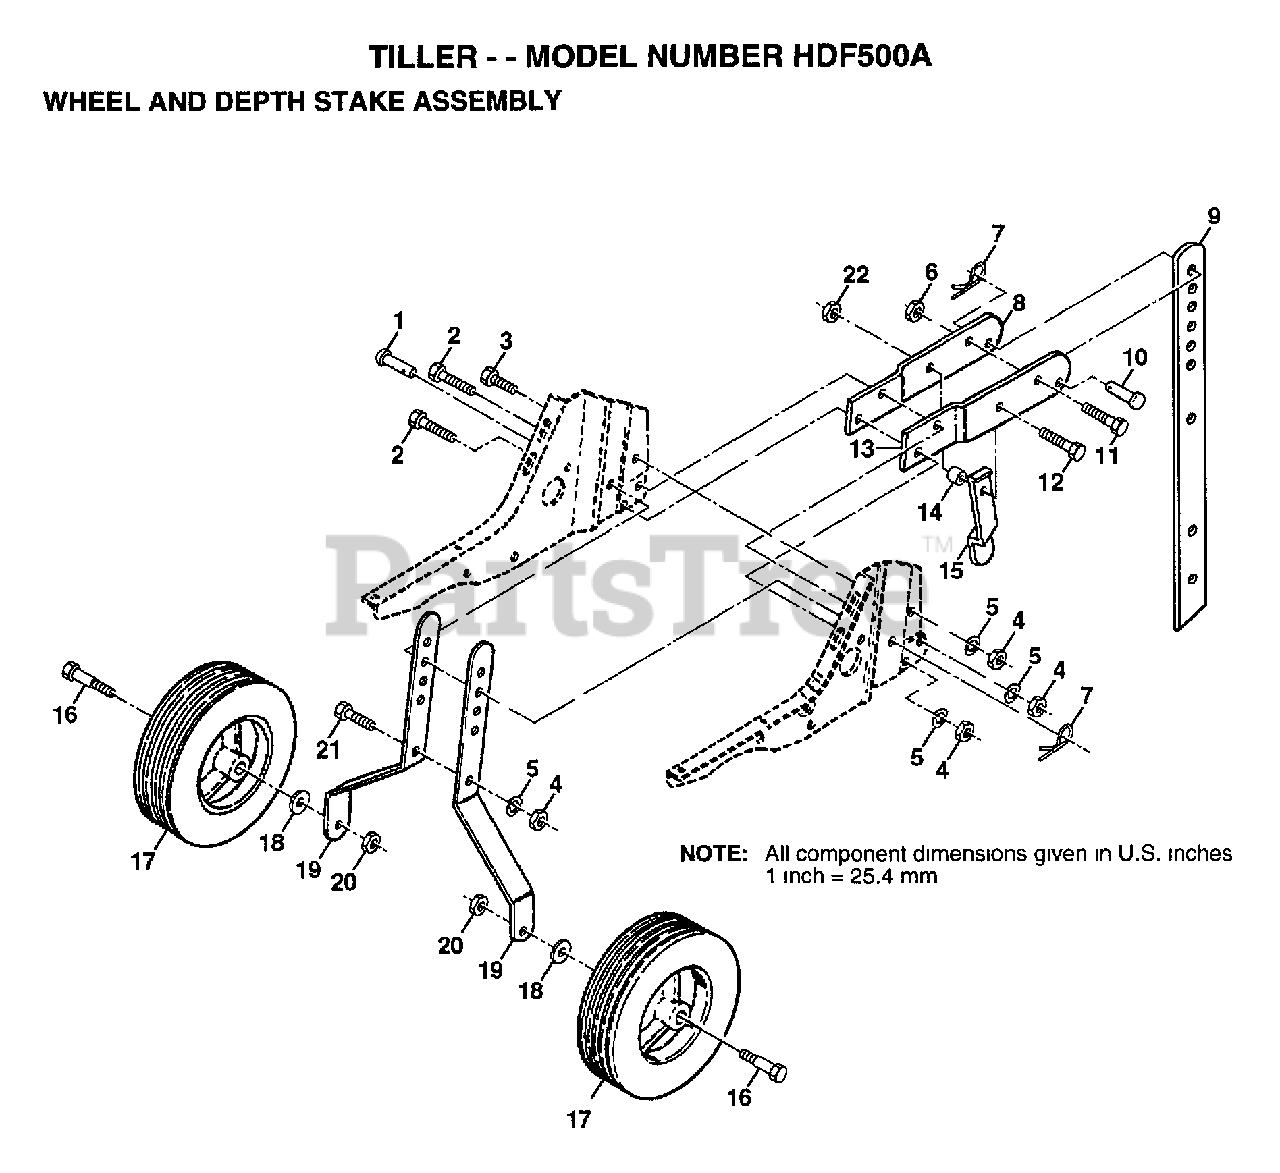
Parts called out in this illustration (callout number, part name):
1	DRILLED RIVET RT
3	BOLT
4	NUT.HEX.5/16-18
5	LOCKWASHER
6	NUT
7	SPRING.RETAINER
11	BOLT
12	BOLT.HEX.5/16-1.5
14	WASHER
15	STAKE SPRING TI
16	BOLT SHOULDER
18	WASHER
22	NUT
